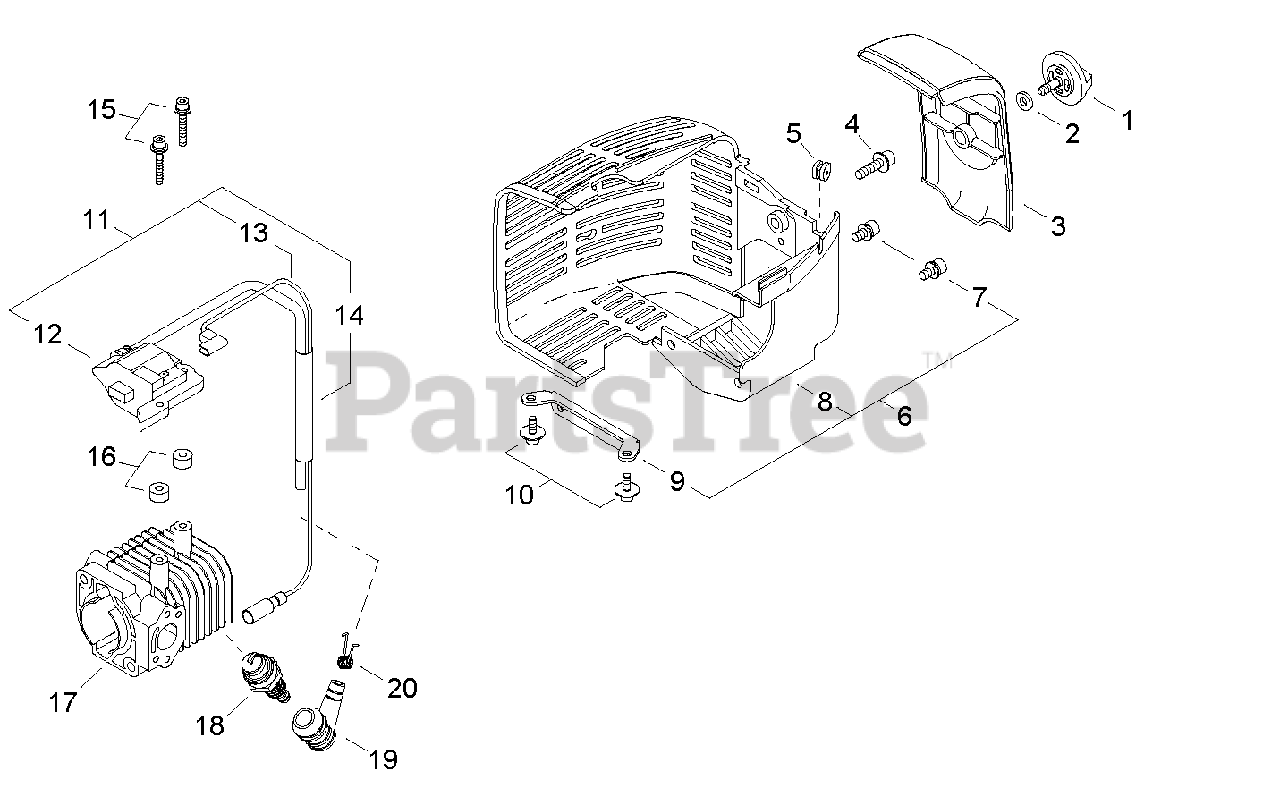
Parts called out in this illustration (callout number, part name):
1	THUMBSCREW
2	WASHER - VINYL
3	COVER, SPARK PLUG
4	SCREW - 5X20
5	GROMMET
6	ENGINE COVER KIT
7	SCREW - 5
8	COVER, ENGINE
9	BRACKET, ENGINE COVER
10	BOLT - 4
11	IGNITION COIL ASSY
12	IGNITION COIL ASSY
13	LEAD - IGNITION
14	TUBE, INSULATOR
15	SCREW - 4X26
16	INSULATOR
17	CYLINDER
18	SPARK PLUG -- BPMR-6A
19	CAP, SPARK PLUG
20	TERMINAL, SPARK PLUG CAP
